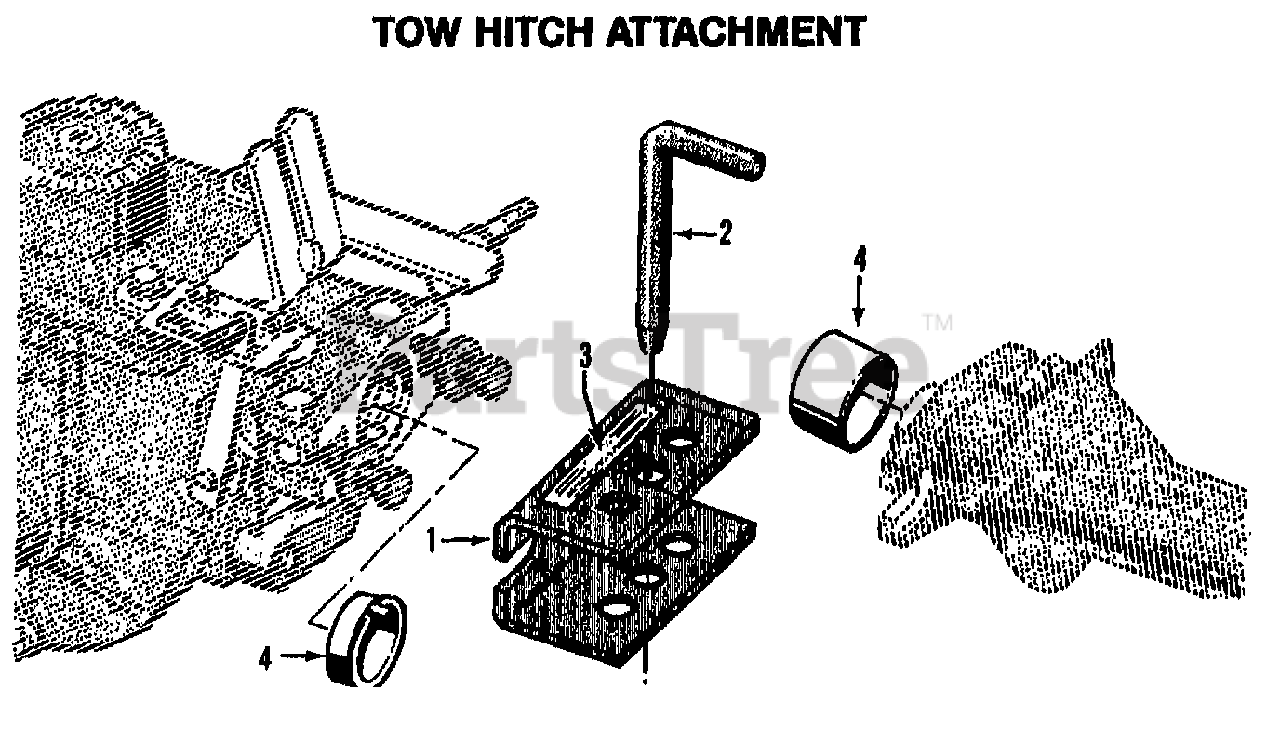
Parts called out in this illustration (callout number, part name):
2	PIN-.625X6.0 ZP
3	DECAL-T/B TOW HITCH
4	KIT-PROTECTIVE END CAPS
